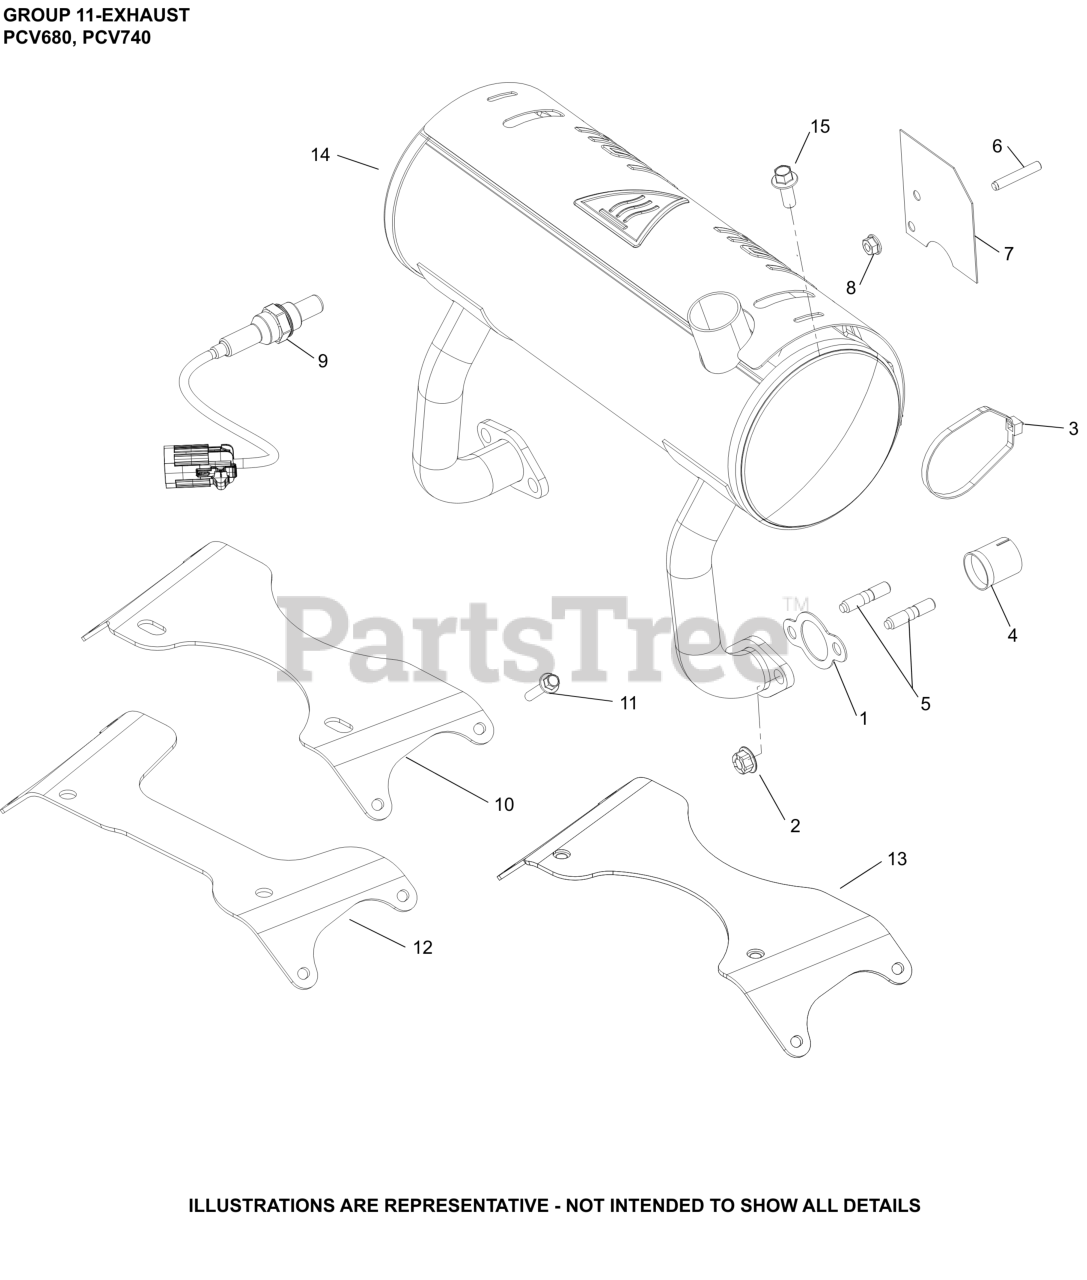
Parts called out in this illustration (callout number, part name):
1	GASKET, EXHAUST
2	NUT, HEX FLANGE LOCK (M8)
4	LINER, EXHAUST PORT
5	STUD, METRIC EXHAUST
6	STUD, M6X1.0X36
7	DEFLECTOR, HEAT
8	NUT, FLG M6X1.0
9	SENSOR, OXYGEN (M18 x 1.5 THREADS)
13	BRACKET, MAIN SUPPORT
14	MUFFLER, VERTICAL CATALYST
15	SCREW, FLG M8X1.25X20
